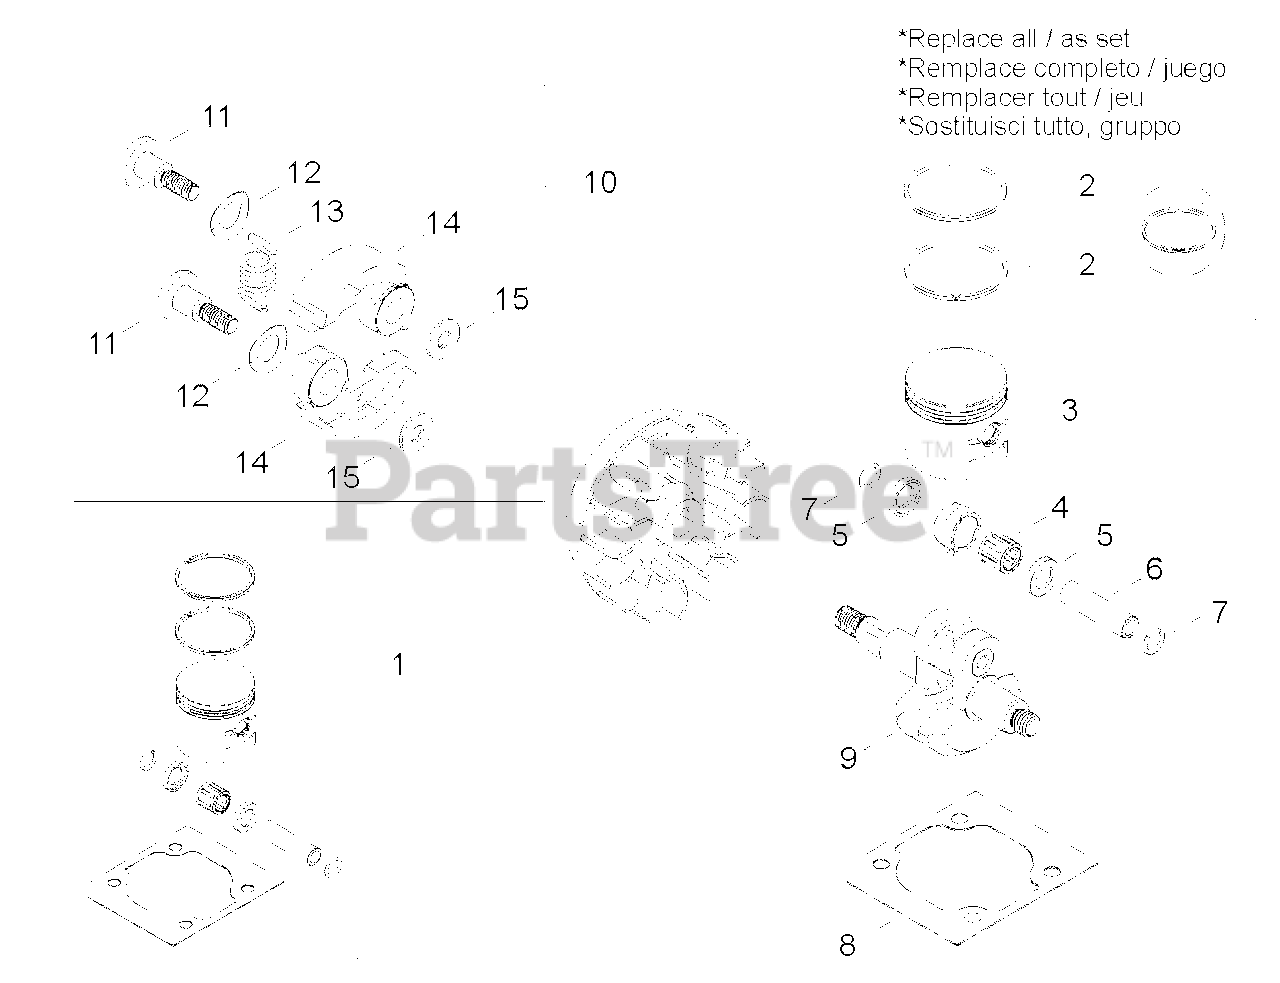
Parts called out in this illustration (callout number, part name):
2	RING, PISTON
3	PISTON
3-1	PISTON KIT
4	BEARING, NEEDLE - 8
5	SPACER, PISTON
6	PIN, PISTON
7	RING, RETAINING
8	GASKET, CYLINDER
9	CRANKSHAFT ASSY
10	CLUTCH ASSY
11	BOLT, CLUTCH
12	WASHER - SPRING
13	SPRING, CLUTCH
14	SHOE, CLUTCH
15	WASHER - 6
